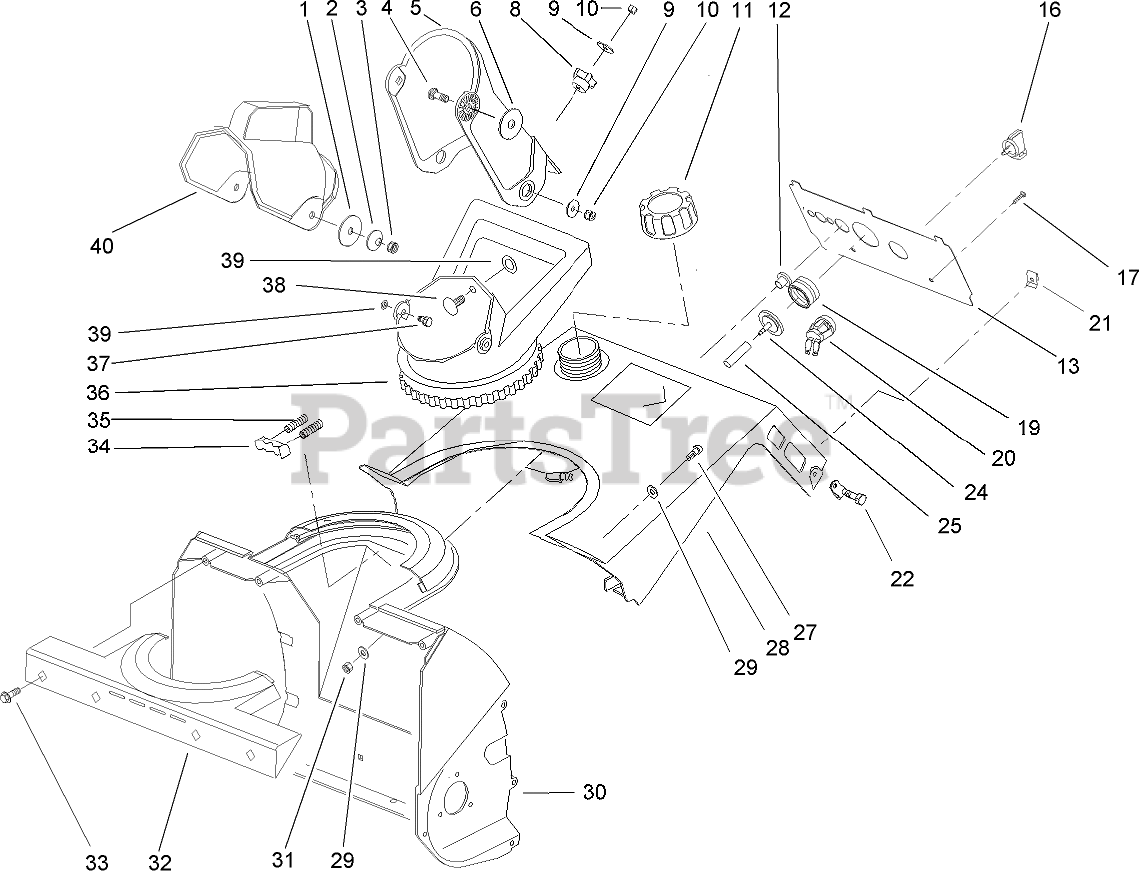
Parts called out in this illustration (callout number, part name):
1	WASHER-FLAT
2	WASHER-BELLEVILLE
3	NUT-LOCK, NI
4	BOLT-CARR
5	CHUTE
6	WASHER-RUBBER
8	KNOB-CHUTE
9	WASHER-FLAT
10	NUT-LOCK, NI
11	GAS CAP ASM
12	GUIDE-ROPE, STARTER
13	PANEL-CONTROL
16	KEY-IGNITION
17	SCREW-SHWH, THREAD FORMING
19	BULB-PRIMER
20	SWITCH
22	SCREW-THREAD FORMING
24	BODY-PRIMER
25	HOSE-PRIMER
27	SCREW-PPH
28	SHROUD-TANK, GAS UPPER
29	WASHER-FLAT
30	HOUSING
31	NUT-LOCK, NI
32	RETAINER-CHUTE
33	SCREW-PLASTIC
34	DETENT-CHUTE
35	SPRING-COMPRESSION
36	HANDLE-CHUTE
37	SCREW-HH
38	SCREW-CARR
39	PUSHNUT-RETAINER, BOLT
40	DEFLECTOR-CHUTE
